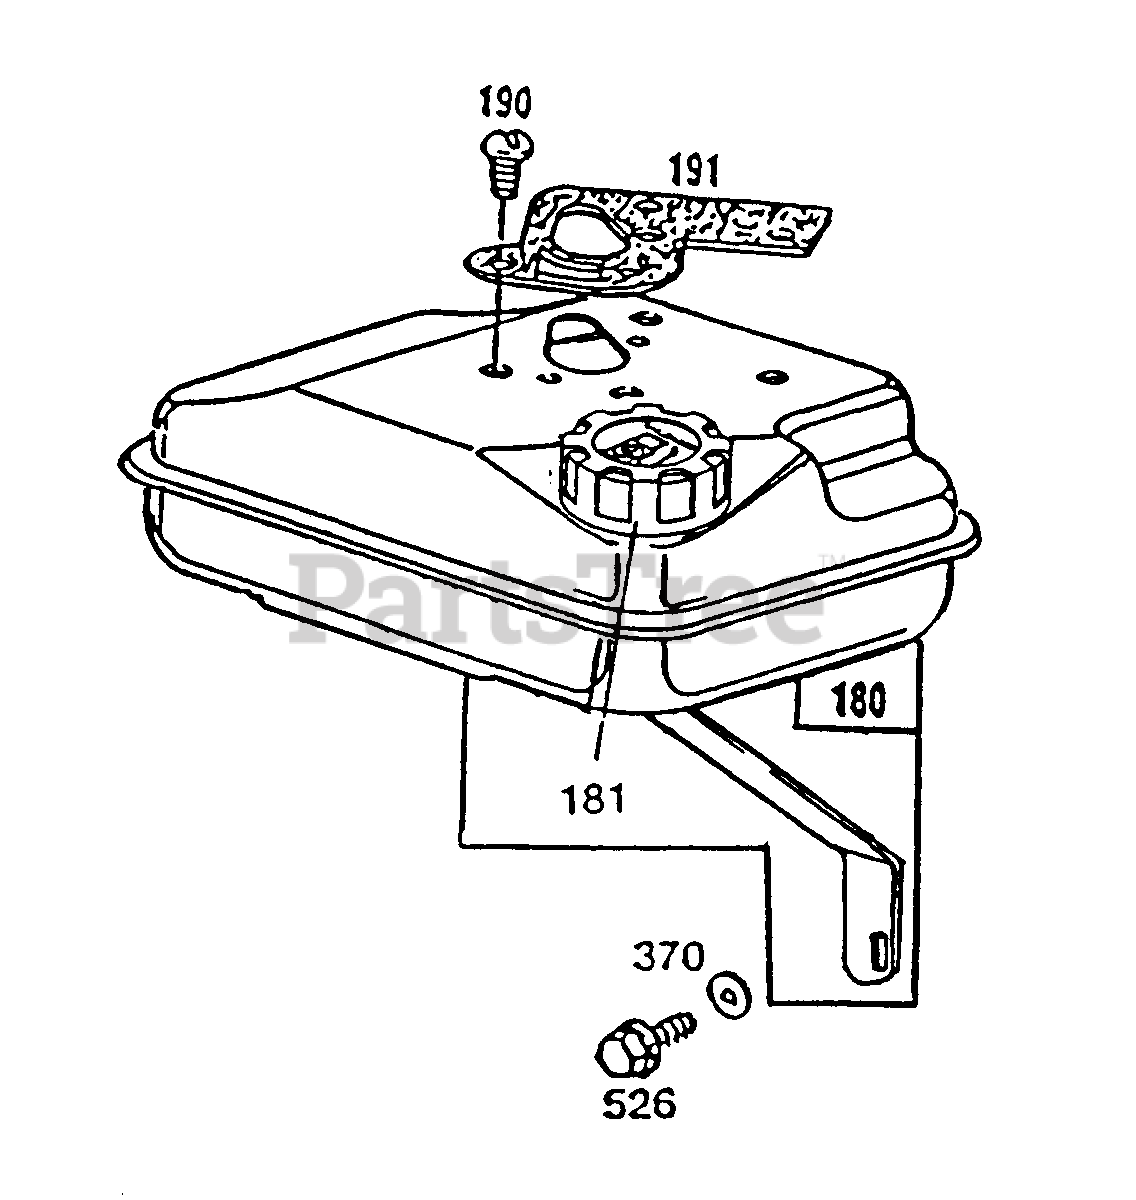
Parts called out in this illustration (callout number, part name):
180	Tank Ass'y.--Fuel
181	Cap--Fuel Tank
190	Screw--Fuel Tank Mounting
191	Gasket--Fuel Tank
370	Washer--Plain
526	Screw--Tank Bracket Mounting
